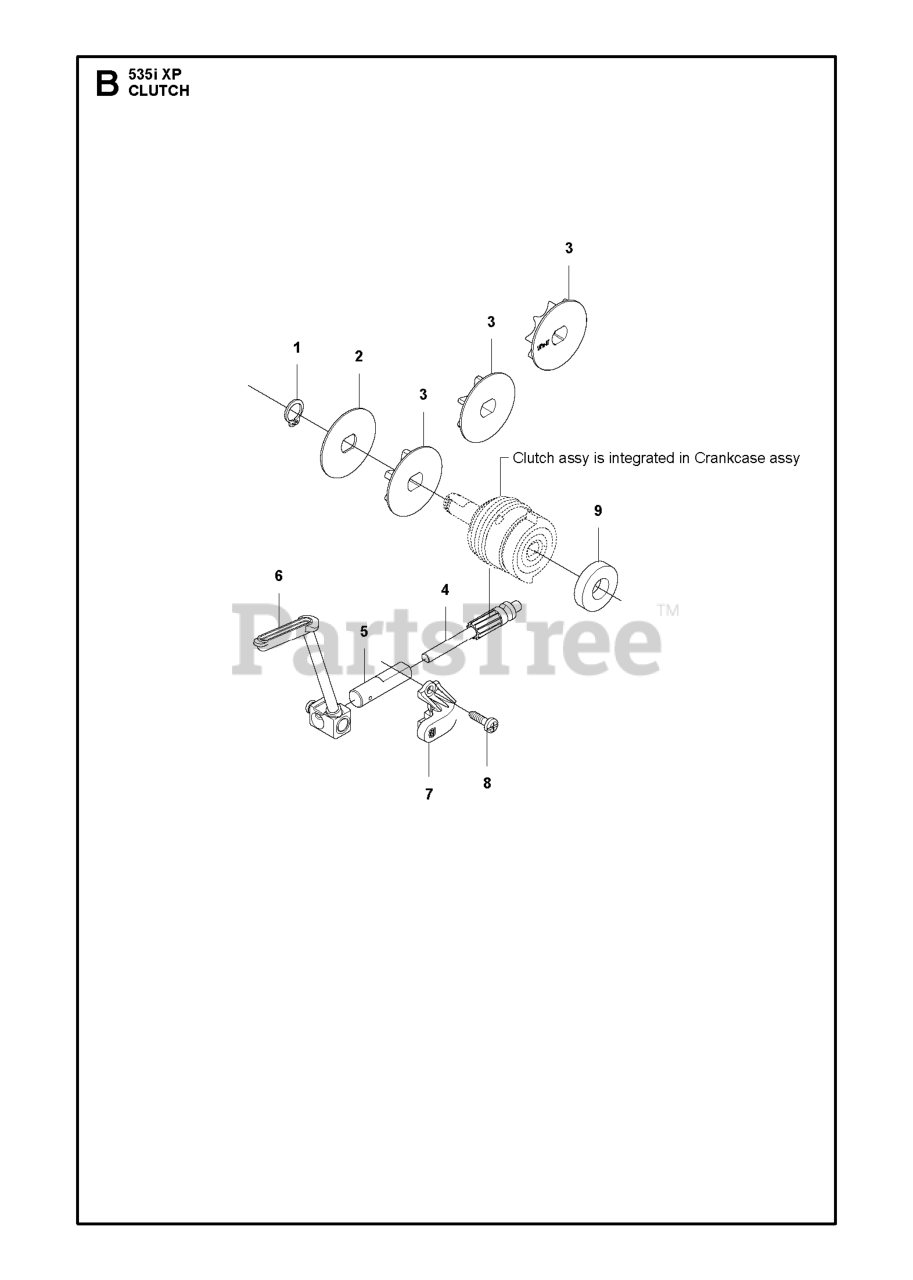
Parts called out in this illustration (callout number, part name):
1	RETAINING RING SGA 10
3	SPUR SPROCKET 1/4IN MINI 9T SP
3	Sprockets
3	SPUR SPROCKET 3/8" - 6T
3	SPUR SPROCKET 1/4" 8T
4	PISTON PUMP
5	PUMP CYLINDER
9	DISTANCE
